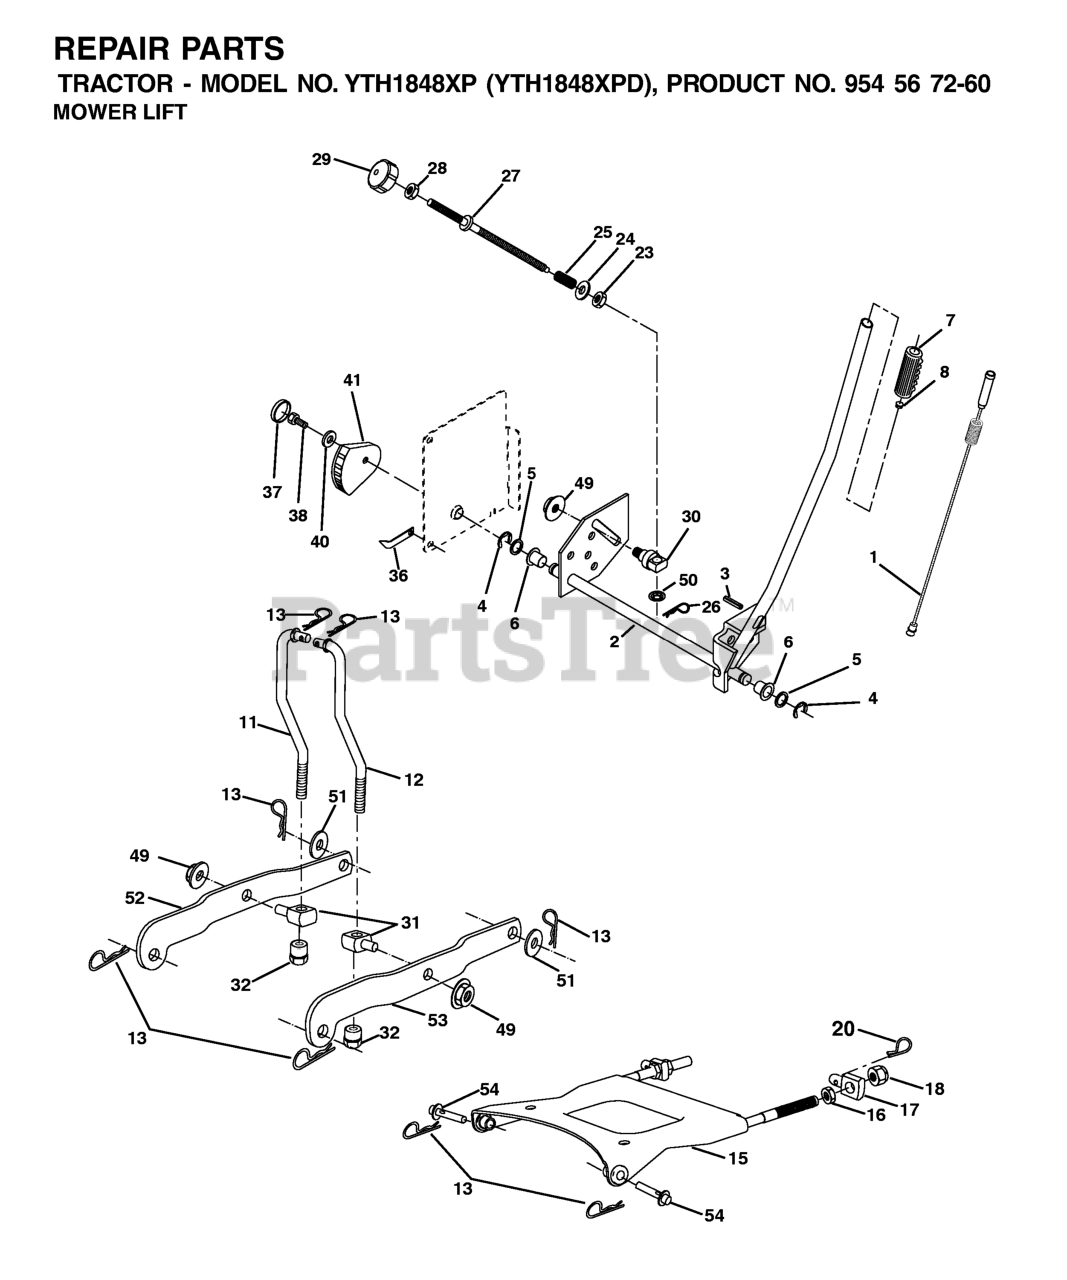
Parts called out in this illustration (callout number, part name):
1	WIRE ASM INNER W/ PLUNGER LT
2	SHAFT ASM R HANDLE
3	PIN GROOVE.
4	RETAINING RING LT
6	BEARING.NYLON
7	GRIP HANDLE
8	PLUNGER BUT KIT
11	LIFT LINK LH
12	LIFT LINK RH
13	RETAINER-SPRNG RB
15	PLATE ASM SUSP FRONT
16	NUT.HEX.JAM.1/2-13
18	NUT.LK.W/WSH.1/2.
20	SPRING RETAINER
25	SPRING**
26	RETAINER CLIP
27	ROD ADJ LIFT
28	NUT
29	KNOB INF 3/8-16
32	NUT, LIFT LINK 7/16-20
36	POINTER, HEIGHT INDICATOR(2 2)
38	SCREW 5/16-18X1
41	IND. HEIGHT STLT
49	NUT
50	NUT PUSH M
51	Washer 1 17/32 X 7/8 X 16 Ga
52	ARM SUSP. REAR LH
53	ARM SUSP REAR RH
54	PIN.FLANGE
